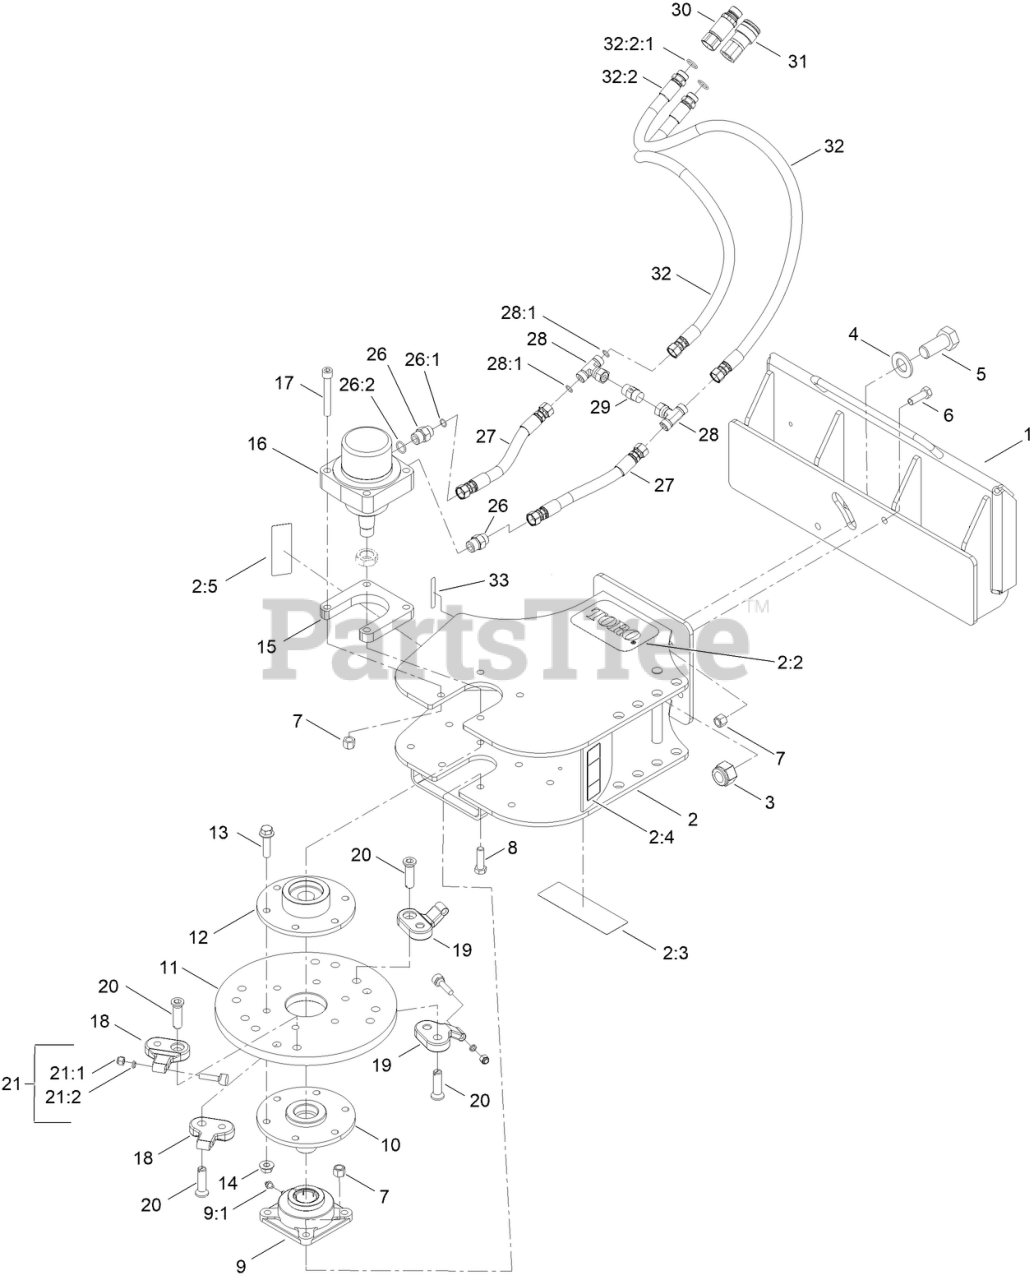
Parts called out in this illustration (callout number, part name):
1	PLATE-ATTACH, QUICK
2	GRINDER FRAME ASM
2:2	DECAL
2:3	DECAL-SAFETY, GRINDER
2:4	DECAL-WARNING
2:5	DECAL-DANGER
3	NUT-HEX, NI
4	WASHER-FLAT
5	SCREW-CAP
6	SCREW-HH
7	NUT-LOCK, NI
8	SCREW-HH
9	BEARING
9:1	FITTING-GREASE
10	SHAFT-STUB
11	WHEEL-GRINDER, STUMP
12	HUB-DRIVE
13	SCREW-HHF
14	NUT-HHF
15	PLATE- SPACER
16	HYD MOTOR ASM
17	SCREW-HSH
18	POCKET-STRAIGHT
19	POCKET-ANGLED
20	BOLT-HSH, RH
21	GRINDER TOOTH ASM
21:1	NUT-LOCK, NI
21:2	SPACER-TOOTH
26	FITTING-STRAIGHT
26:1	O-RING
26:2	O-RING
27	HYD HOSE ASM
28	FITTING-TEE
28:1	O-RING
29	VALVE-CHECK
30	NIPPLE-CONNECT, PRESSURE
31	COUPLER-FACE, FLUSH
32	HYD HOSE ASM
32:2	FITTING-STRAIGHT
32:2:1	O-RING
33	DECAL-WARNING
